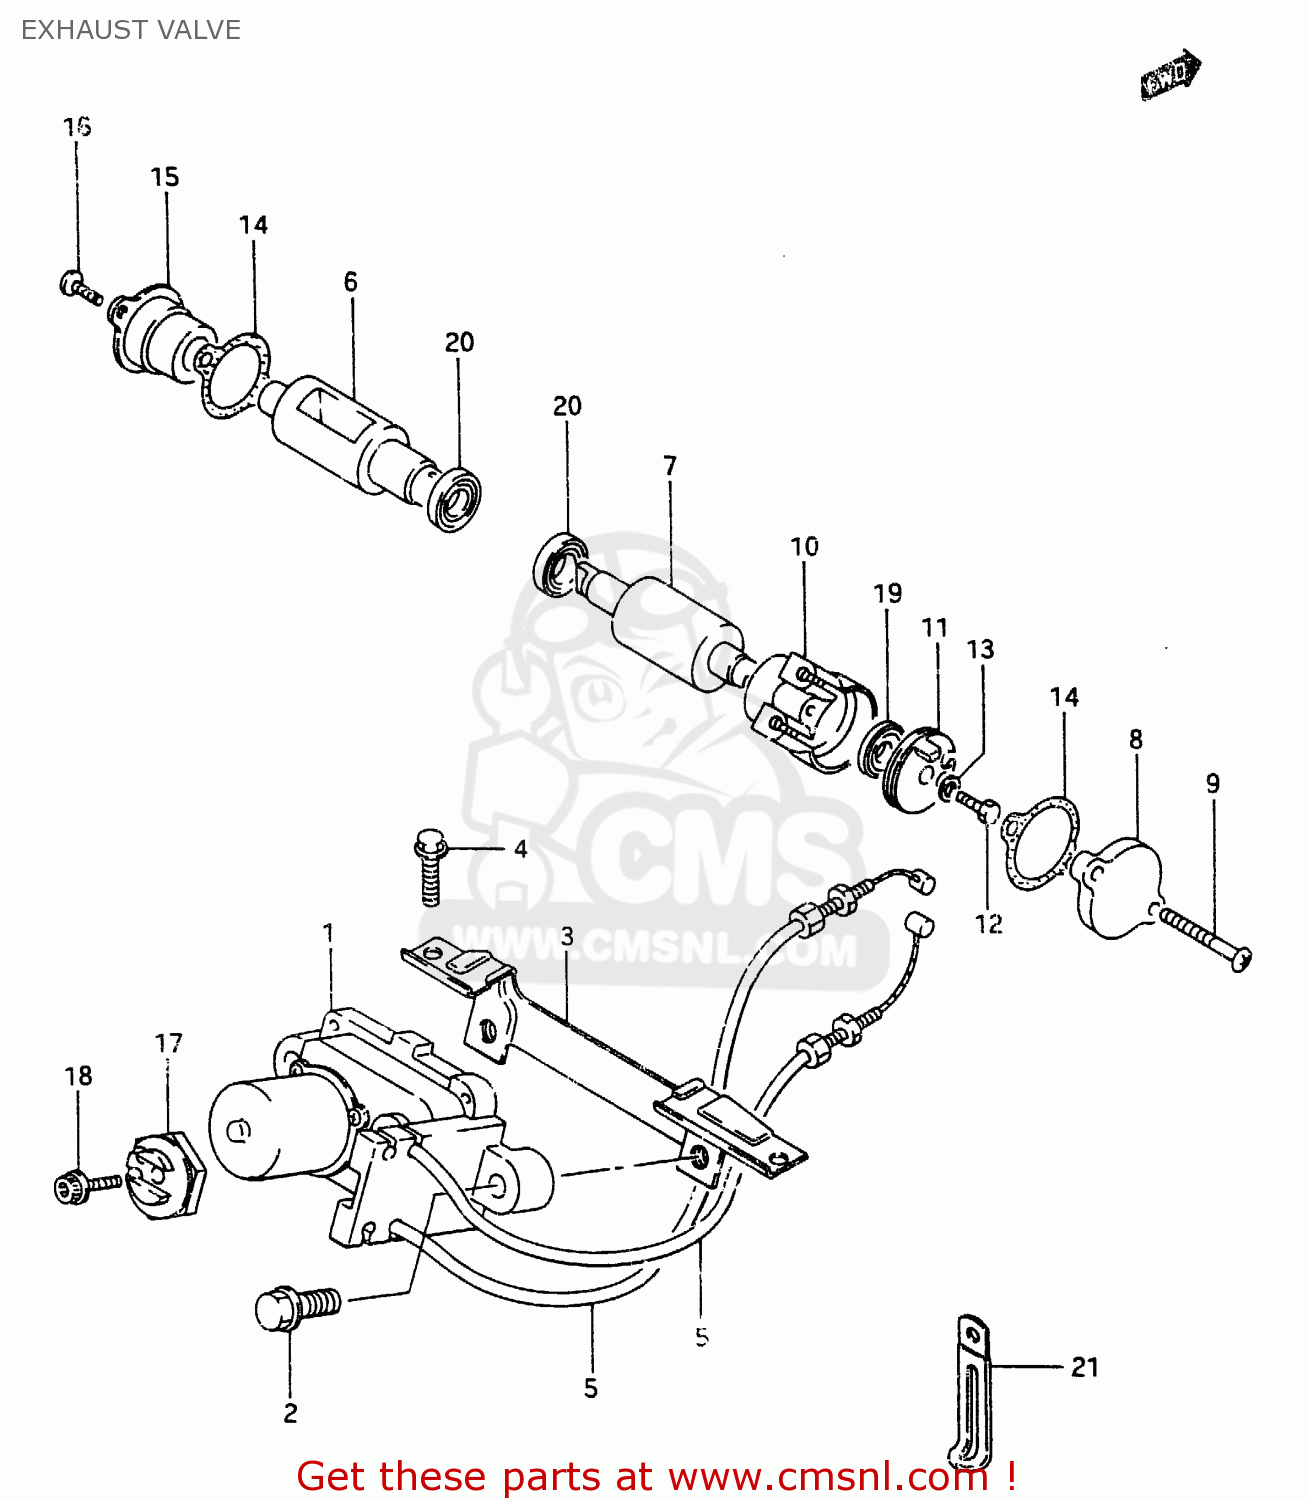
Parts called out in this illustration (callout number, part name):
1	ACTUATOR ASSY,EXHAUST VALVE
2	BOLT
3	BRACKET, ACTUATOR
4	BOLT
5	CABLE ASSY,EXHAUST VALVE
6	VALVE, EXHAUST LH
7	VALVE, EXHAUST RH
8	COVER,HOLDER
9	SCREW
10	HOLDER, EXHAUST VALVE
11	PULLEY, EXHAUST VALVE
12	BOLT
13	WASHER
14	GASKET, EXHAUST VALVE (MCA)
15	CAP, EXHAUST VALVE
16	SCREW
17	PULLEY, CONTROLLER
18	BOLT
19	SEAL,OIL(12X22X5)
20	SEAL,OIL(16X26X7)
21	CLAMP
